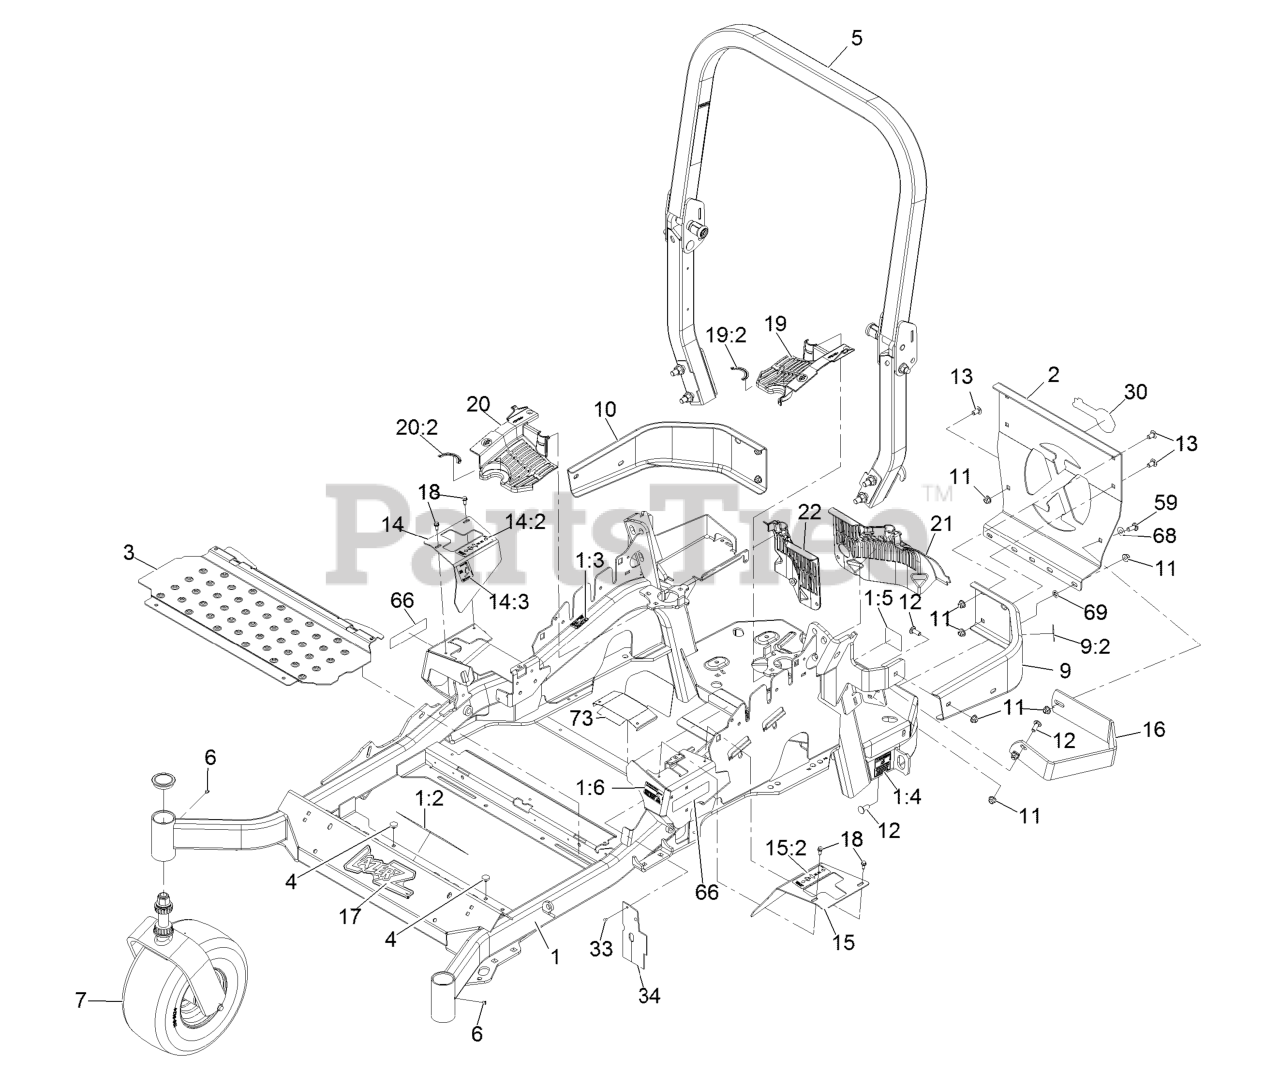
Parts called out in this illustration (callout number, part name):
1	MAINFRAME ASM
1:2	DECAL-SLOPE
1:3	DECAL-CAUTION
1:4	DECAL-BELT DRIVE
1:5	DECAL-SPARK ARRESTER
1:6	DECAL-FUEL FILL
2	PLATE,REAR GUARD
5	ASM,ROPS SERVICE EXMARK
7	Caster Wheel Asm
9	LH BUMPER ASM
9:2	DECAL-CAUTION
10	BUMPER-RH
11	NUT-HF, NI
12	SCREW-CARR
13	SCREW-CARR
14	RH MOTION CONTROL COVER ASM
14:2	DECAL-MOTION CONTROL
14:3	DECAL-PARK BRAKE
15	LH MOTION CONTROL COVER ASM
15:2	DECAL-MOTION CONTROL
17	DECAL,LAZER MODEL
18	SCREW-HWH
19	LH HYDRO GUARD ASM
19:2	DECAL-HYDRO OIL
20	RH HYDRO GUARD ASM
20:2	DECAL-HYDRO OIL
21	GUARD-HYDRO REAR, LH TRIM
22	GUARD-HYDRO, REAR (RH)
33	RIVET-POP
34	DEFLECTOR-AIR FLOW
59	SCREW-HH
66	DECAL-X-SERIES
68	WASHER-FLAT
69	NUT-PUSH
73	GUARD-EXHAUST
